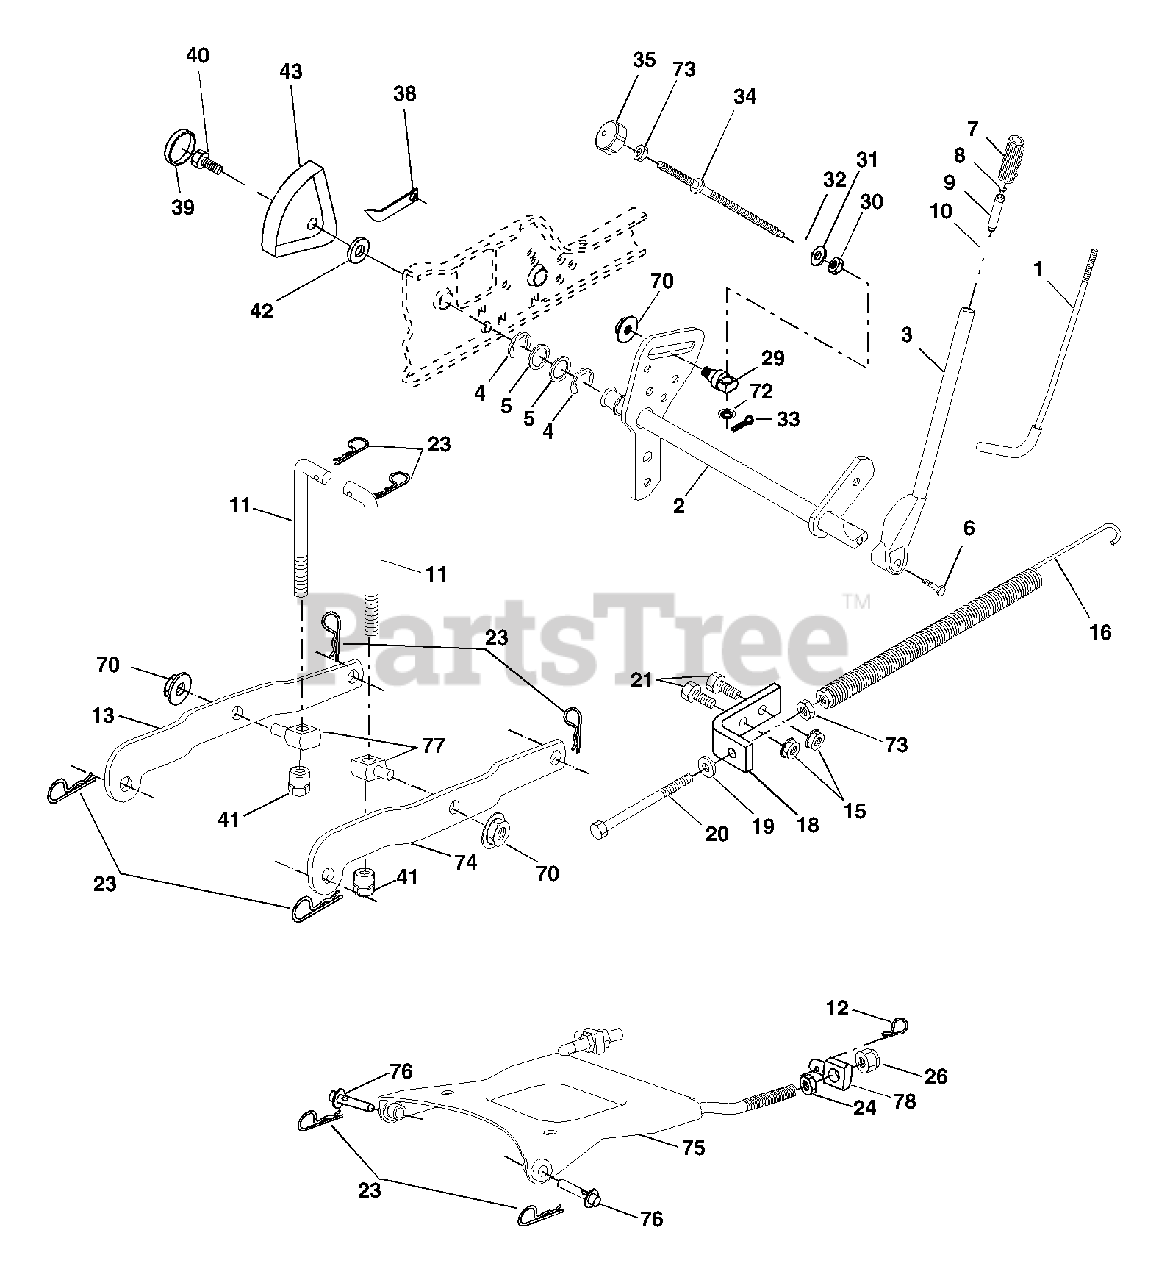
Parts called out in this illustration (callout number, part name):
1	Rod Asm., Lever
2	Shaft Asm., Lift Vgt
3	Lever Asm., Lift Rh
4	E-Ring Truarc #5133-87
5	Washer 29/32 x 1-1/4 x 16 Ga.
6	Bolt, Fin Hex 3/8-16 x 1-1/2
7	Grip, Handle Fluted
8	Button, Plunger
9	Plunger, Lever Lift
10	Spring 2-1/8"
11	Link Lift
12	Retainer,Spring
15	Nut, Crownlock 3/8-16 Unc
16	Spring Asm., Assist Lift
18	Bracket, Spring Assist
19	Washer 13/32 x 13/16 x 16 Ga.
20	Bolt, Adjust Spring Assist
21	Bolt, Fin Hex 3/8-16 x 1
23	Retainer,Spring
24	Nut, Jam Hex 1/2-13 Unc
26	Nut, Crownlock 1/2-13 Unc
29	Trunnion Inf. Height
30	Nut, Special
31	Washer 13/32 x 5/8 x 16 Ga.
32	Spring, Compression Inf Hgt
33	Pin, Cotter 3/32 x 1/2
34	Rod, Adj Lift
35	Knob, Inf 3/8-16 Unc
38	Pointer, Height Indicator
39	Plug, Hole
40	Screw 5/16-18 x 3/4
41	Nut, Lift Link 7/16-20
42	Washer 11/32 x 1-1/2 x 10 Ga.
43	Scale, Indicator Height
70	Nut, Hexflange Lock
72	Nut, Push Phos & Oil
73	Nut Hex Jam 3/8-16 Unc
74	Arm Susp. Rear RH
75	Plate Asm Susp. Front
76	Pin Flange
77	Trunnion Susp. Arm
78	Trunnion Susp. Front
79	Arm Susp. Rear LH
